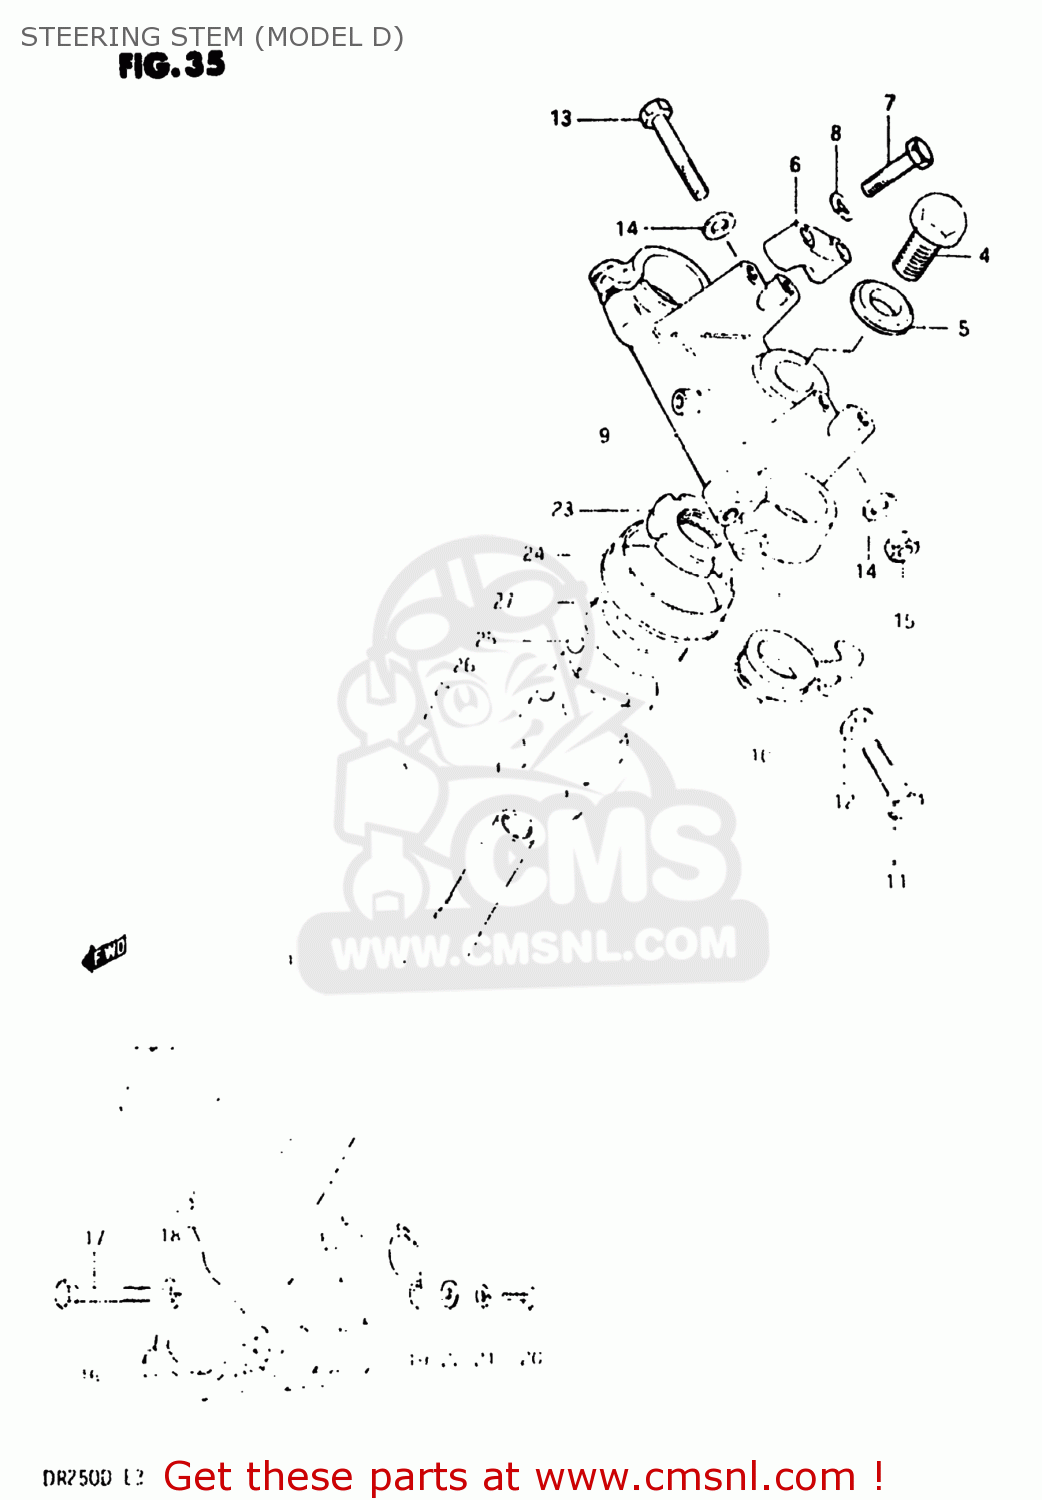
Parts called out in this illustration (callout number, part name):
1	STEM,STEERING
2	BEARING
3	WASHER,THRUST
4	BOLT
5	WASHER
6	HOLDER,HANDLEBAR
7	BOLT
8	LOCK WASHER
9	HEAD,STEERING STEM
10	GUIDE,CABLE
11	BOLT
12	LOCK WASHER
13	BOLT 8X50
14	WASHER
15	NUT
16	GUIDE,CABLE
17	BOLT 8X45
18	LOCK WASHER
19	CLIP
20	SCREW
21	LOCK WASHER
22	WASHER
23	NUT,STEERING STEM
24	SEAL,STEERING UPR DUST
25	BALL
26	RACE,STEERING,INNER,UPPER
27	RACE,STEERING,OUTER,UPPER
